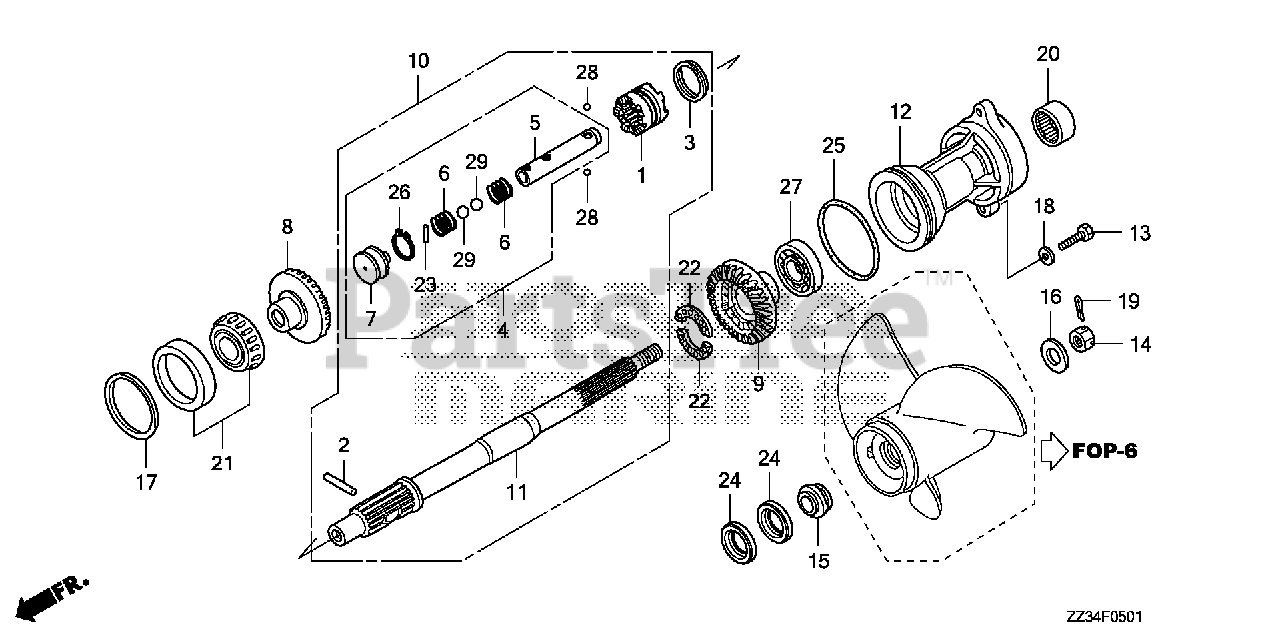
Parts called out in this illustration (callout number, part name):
1	SHIFTER, CLUTCH (POWER THRUST)
2	PIN, SHIFTER (8X47)
3	RING, CROSS PIN
4	SLIDER, SHIFT (POWER THRUST)
5	SLIDER, SHIFT (POWER THRUST)
6	SPRING, SHIFT (POWER THRUST)
7	PLATE, SHIFT
8	GEAR, FR. BEVEL (28T) (POWER THRUST)
9	GEAR, RR. BEVEL (28T) (POWER THRUST)
10	SHAFT ASSY., PROPELLER (POWER THRUST)
11	SHAFT, PROPELLER (POWER THRUST)
12	HOLDER, PROPELLER SHAFT *NH282MU* (OYSTER SILVER METALLIC-U)
13	BOLT, HEX. (10X40)
14	NUT, CASTLE (18MM)
15	WASHER, PROPELLER THRUST
16	WASHER, PLAIN (18.5MM)
17	SHIM A, BEVEL (0.10) (FR)
17	SHIM B, BEVEL (0.15) (FR)
17	SHIM C, BEVEL (0.30) (FR)
17	SHIM D, BEVEL (0.50) (FR)
18	WASHER, PLAIN (10MM)
19	PIN, SPLIT (4.0)
20	BEARING, NEEDLE (30X37X26)
21	BEARING, TAPERED ROLLER (50X82X21.5)
22	BEARING, BALL (28X38X3)
23	ROLLER (3X12.8)
24	SEAL, WATER (30X45X7)
25	O-RING (94X4.1)
26	CIRCLIP, OUTER (14MM)
27	BEARING, RADIAL BALL (6208)
28	BALL, STEEL (#7) (7/32)
29	BALL, STEEL (#11) (11/32)
